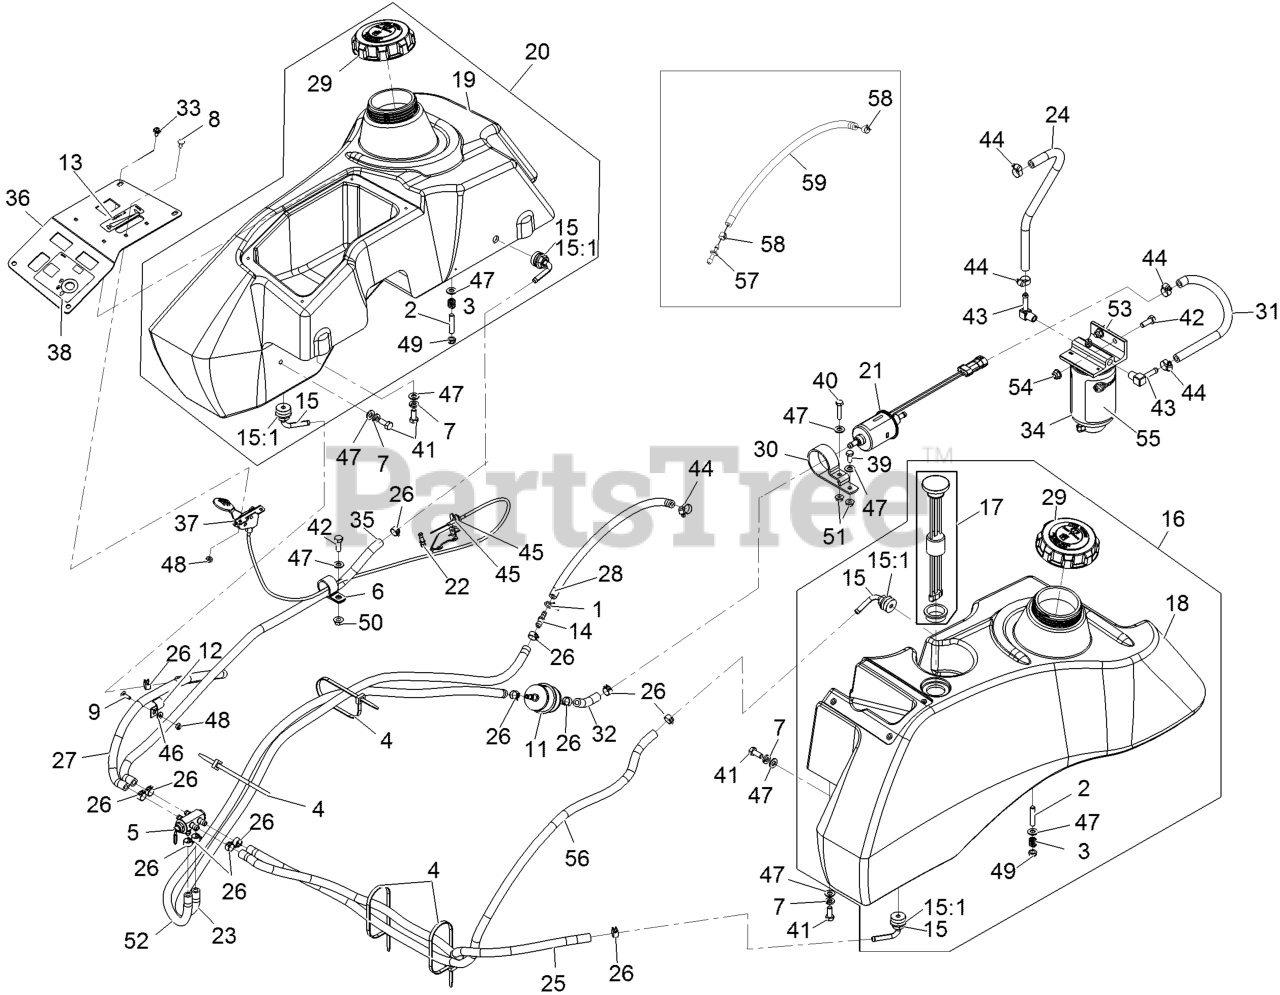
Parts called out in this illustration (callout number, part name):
2	STUD
3	SPRING-TANK, FUEL
4	TIE-PLASTIC
5	VALVE,FUEL SELECTOR 5/16
6	CLIP-LOOM
7	WASHER-LOCK
8	BOLT-CARR
9	BOLT-CARR
11	FILTER-INLINE
12	CLIP-HALF, LOOM
13	DECAL,THROTTLE ONLY
14	CONNECTOR
15	FITTING,FUEL BULKHEAD W/O
15:1	O-RING,BULKHEAD FITTING
16	ASM,FUEL TANK LXS LH
17	KIT, CT FUEL GAGE REPL.
18	ASM, Fuel Tank Lxs LH
19	Asm, Fuel Tank Lxs Rh
20	ASM, FUEL TANK LXS RH
21	PUMP-FUEL
22	SWIVEL-STOP, CABLE
23	HOSE-FUEL
24	HOSE-FUEL
25	HOSE-FUEL
26	CLAMP-HOSE
27	HOSE-FUEL
28	HOSE-FUEL
29	CAP-BIODIESEL
30	BRACKET-PUMP, FUEL
31	HOSE-FUEL
32	HOSE-FUEL
33	SCREW-PPH
34	FILTER-FUEL
35	HOSE-FUEL
36	CONTROL PANEL W/DECALS
37	CABLE,THROTTLE
38	DECAL-CONTROL PANEL
39	SCREW-HH
40	SCREW-HH
41	SCREW-HH
42	SCREW-HH
43	FITTING-HYD, 90 DEG
44	CLAMP-WORM
45	NUT-JAM
46	WASHER-FLAT
47	WASHER-PLAIN
48	NUT-LOCK, NI
49	NUT-LOCK, NI
52	HOSE-FUEL
53	FUEL FILTER ASM
54	NUT-HF, NI
55	Decal,Exmark Filter
56	HOSE-FUEL
57	FITTING-STRAIGHT
58	CLAMP-HOSE
59	HOSE-FUEL
